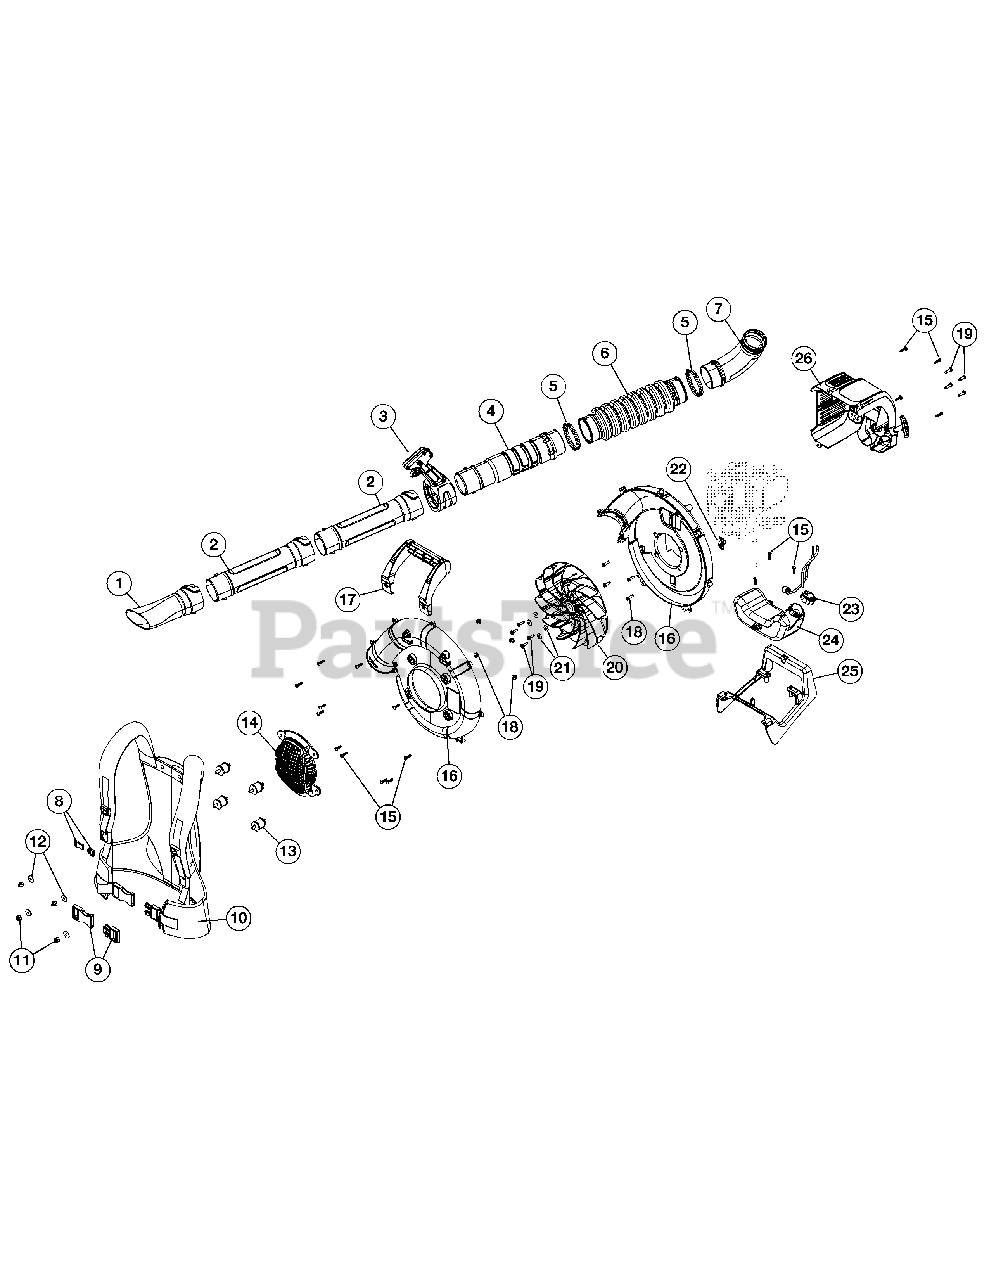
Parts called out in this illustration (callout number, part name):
1	Nozzle
2	Lower Blower Tube
3	Throttle Grip Assembly
4	Upper Blower Tube
5	Clamp
7	Elbow Tube
8	Upper Harness Clip
9	Lower Harness Clip
10	Harness (includes 8 & 9)
11	Nut
12	Spacer
13	Insulator Mount
14	Intake Cover
15	Screw
16	Impeller Housing Assembly
18	Nut
19	Screw
20	Impeller (includes 19)
22	Throttle Retaining Clip
24	Fuel Tank Assembly (includes 23)
26	Engine Cover Assembly
